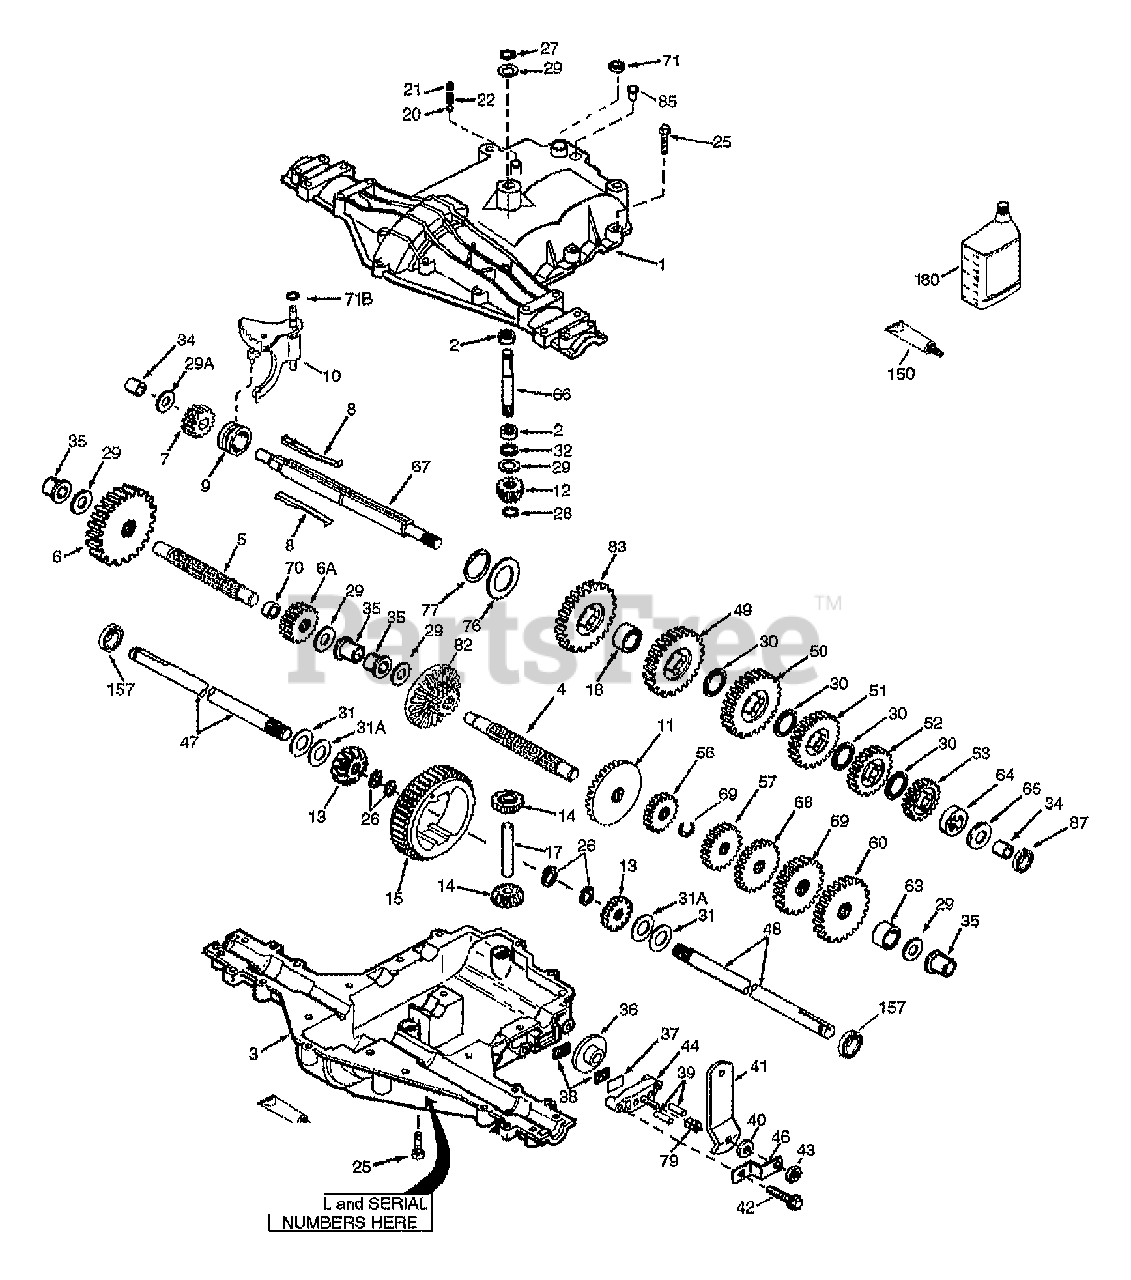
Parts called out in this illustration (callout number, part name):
2	NEEDLE BEARING
4	COUNTERSHAFT
5	OUTPUT SHAFT
6	SPUR GEAR
6A	SPUR GEAR
7	SPUR GEAR
8	SHIFT KEY
10	ROD & FORK
11	BEVEL GEAR
12	BEVEL GEAR
13	BEVEL GEAR
14	BEVEL GEAR
15	RING GEAR
17	DRIVE PIN
22	SPRING
26	RET RING
27	RET RING
28	RET RING
29	WASHER
30	WASHER
32	OIL SEAL
36	BRAKE DISK
37	BRAKE PAD PLATE
38	BRAKE PAD
39	DOWEL PIN
41	BRAKE LEVER
49	SPUR GEAR
50	SPUR GEAR
51	SPUR GEAR
52	SPUR GEAR
53	SPUR GEAR
56	SPUR GEAR
57	SPUR GEAR
58	SPUR GEAR
59	SPUR GEAR
60	SPUR GEAR
66	INPUT SHAFT
67	BRAKE SHAFT
69	RET RING
82	BEV & SPUR GEAR
83	SPUR GEAR
87	OIL SEAL
150	LIQUID GASKET RTV SILICONE
157	OIL SEAL
180	OIL 80W90
